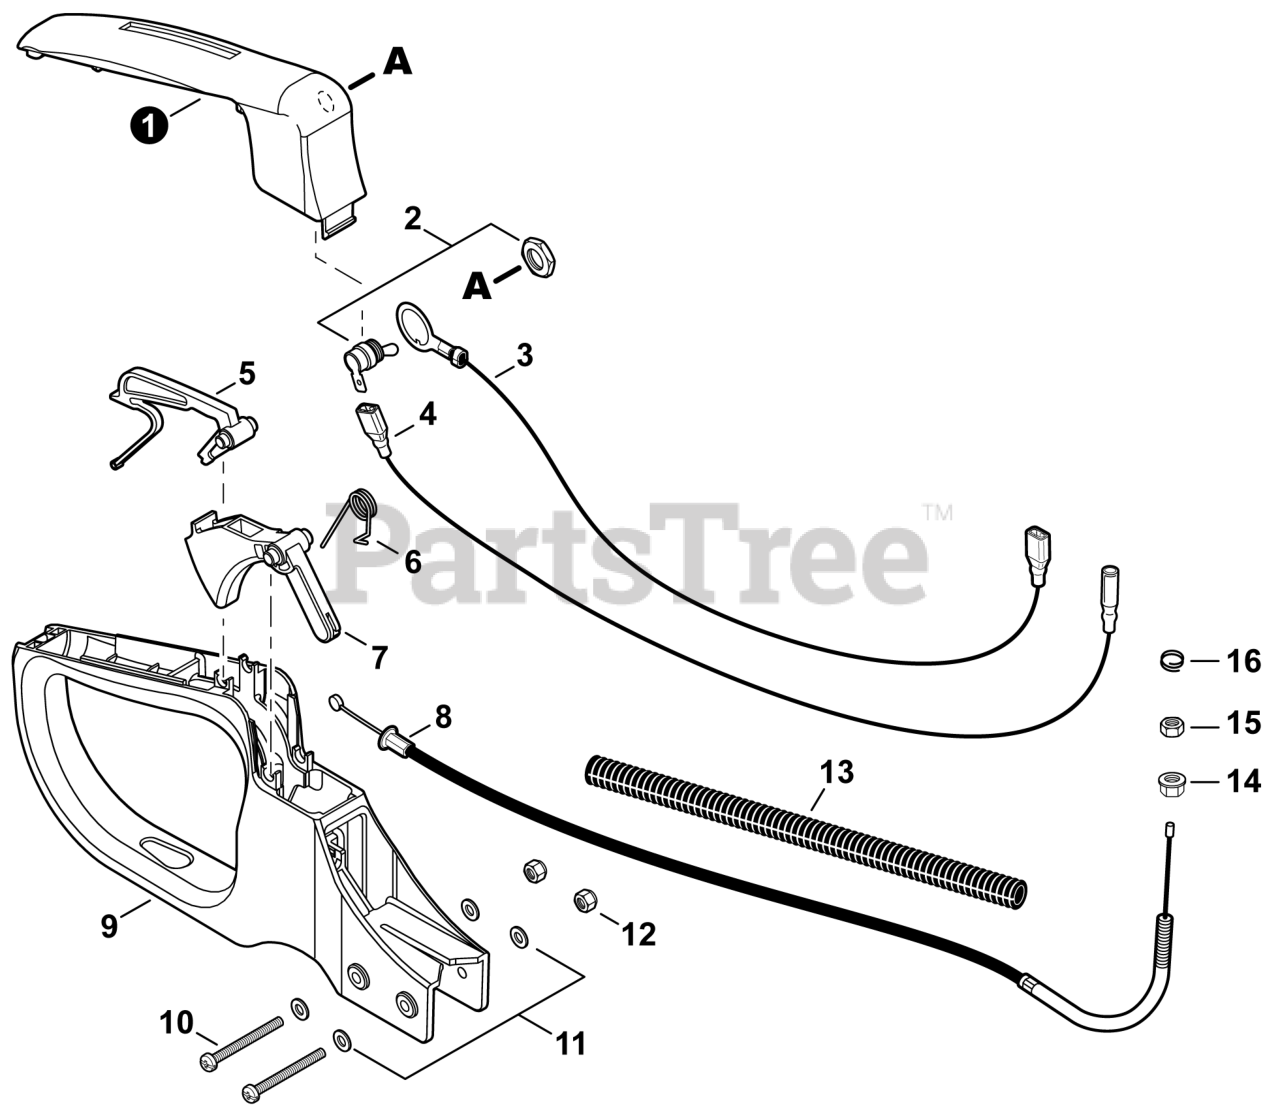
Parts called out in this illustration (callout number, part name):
1	COVER, HANDLE
2	SWITCH, ON-OFF
3	LEAD - GROUND
4	LEAD - IGNITION
5	LOCKOUT, THROTTLE
6	SPRING, TORSION
7	TRIGGER, THROTTLE
8	CABLE, THROTTLE
9	HANDLE, REAR - BLACK (HC-155)
10	SCREW 5x45
11	WASHER, FLAT 5.5x10x0.8
12	NUT, LOCK M5
13	TUBE, FLEXIBLE
14	NUT, FLANGE M6
